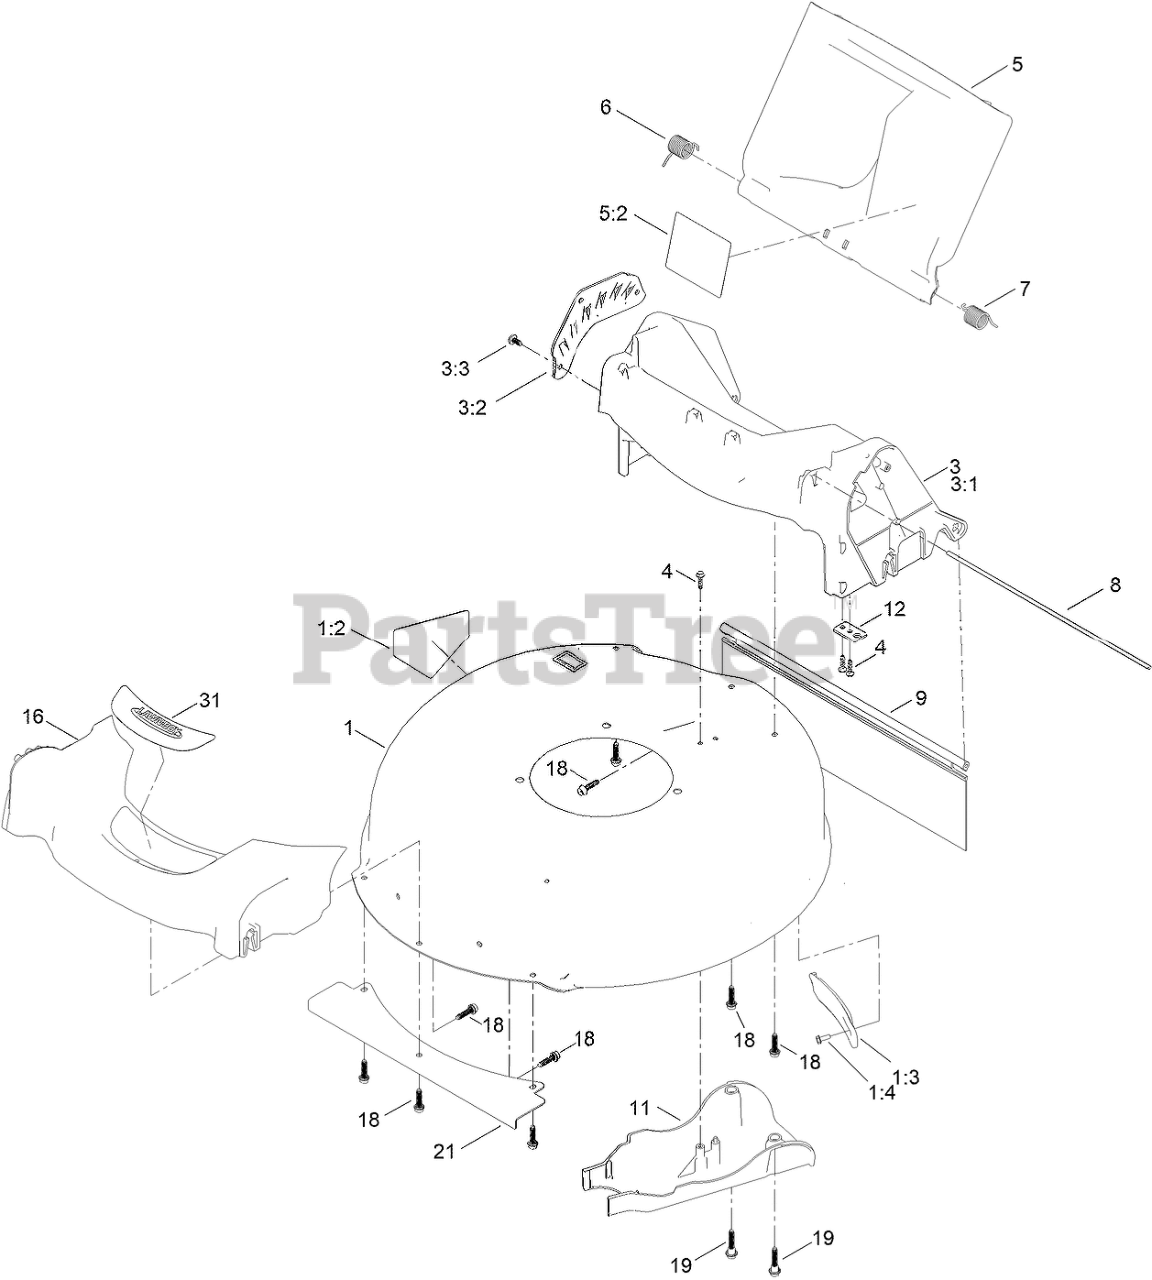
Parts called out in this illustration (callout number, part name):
1	HOUSING ASM
1:2	DECAL-DANGER
1:3	COVER-BELT
1:4	SCREW-TAPTITE
3	CHUTE ASM
3:1	CHUTE-SP/AWD, 21 IN
3:2	PLATE-HOC
3:3	SCREW-PLASTIC,PH
4	SCREW-PLASTIC, HWH
5	REAR DEFLECTOR ASM
5:2	DECAL-WARNING
6	SPRING-TORSION
7	SPRING-TORSION
8	ROD-DOOR
9	SHIELD-TRAILING
11	COVER-BELT
12	BRACKET-CABLE
16	BUMPER
18	SCREW-FLANGE, PLASTIC
19	SCREW-SHOULDER, HHF
21	SHIELD-FRONT
31	DECAL-DECK
